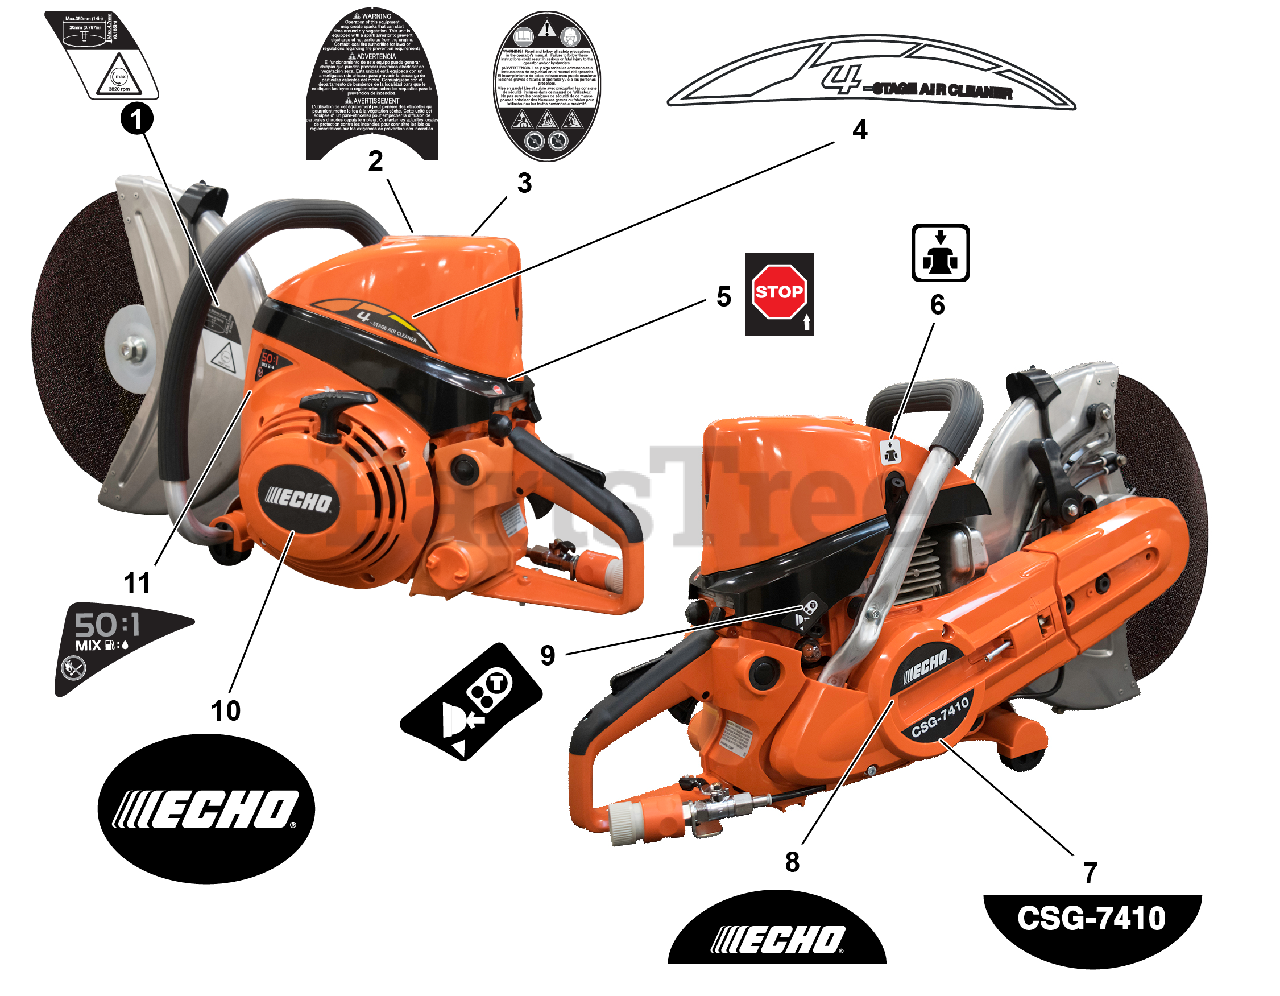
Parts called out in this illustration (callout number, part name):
1	LABEL, CAUTION
2	LABEL, CAUTION
3	LABEL, CAUTION
4	LABEL - AIR FILTER
5	LABEL, STOP
6	LABEL - DECOMPRESSION
7	LABEL, MODEL - CGS-7410
8	LABEL, ECHO
9	LABEL, PURGE PUMP
10	LABEL, ECHO
